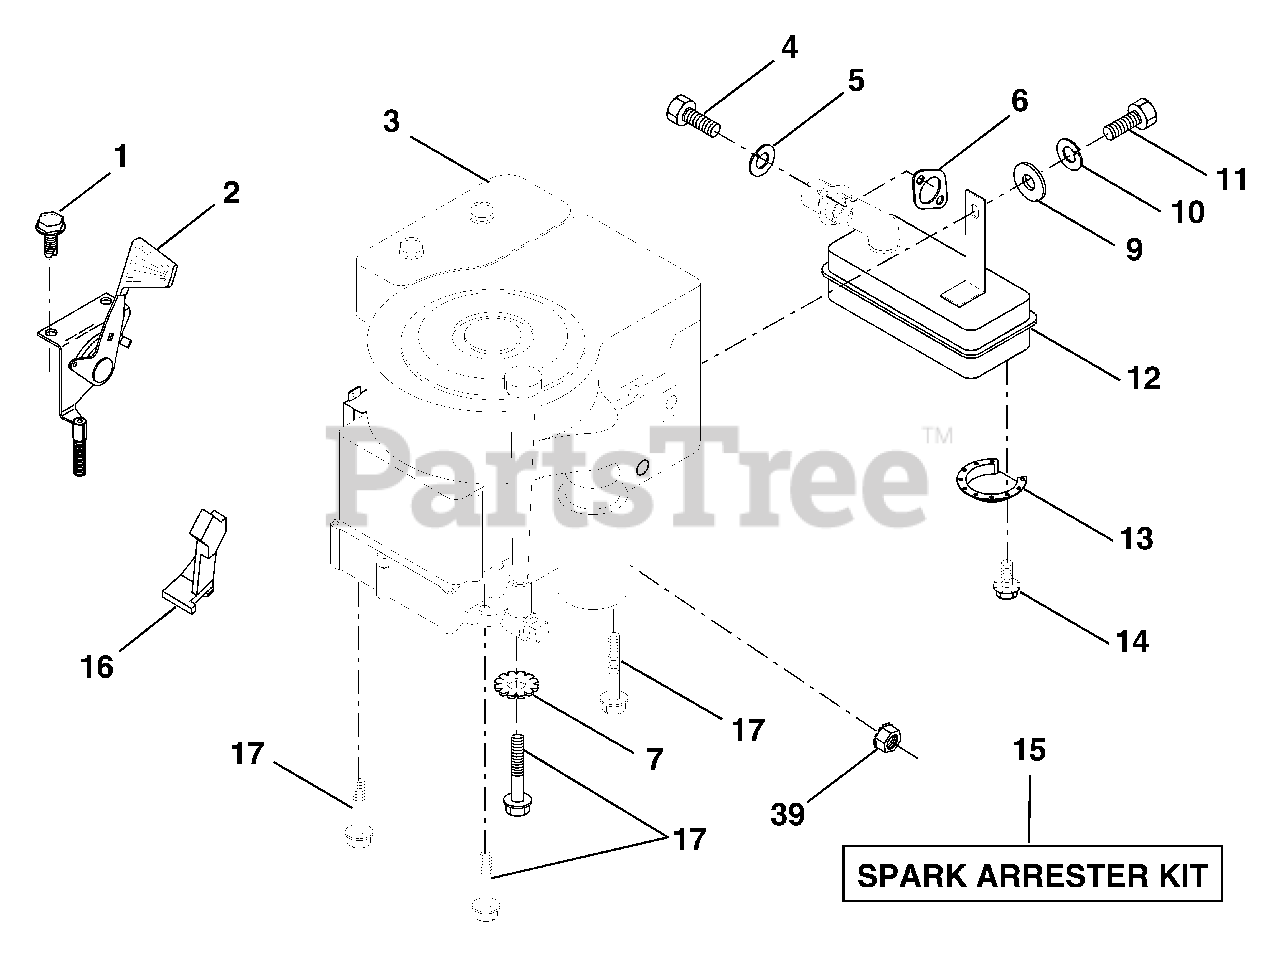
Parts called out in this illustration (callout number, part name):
1	Screw, Hex Thd. Cut 1/4-20 x 1/2
2	Control, Throttle
4	Screw, Hex, Cap 5/16-18 x 3/4
5	Washer, Lock Heavy Helical Spring 5/16
6	Gasket, Exhaust
7	Washer Ext. Tooth 3/8
9	Washer 5/16 x 3/4 x 16
10	Washer, Lock Hvy Hlcl Spring 1/4
11	Bolt, Hex Fin.
13	Deflector, Muffler
14	Screw, Spiderloc
15	Arrester, Spark
16	Stop, Throttle
17	Screw, Hex Washer Head, Thdrol. 3/8-16 x 1-1/2
39	Nut, Flange 1/4-20
